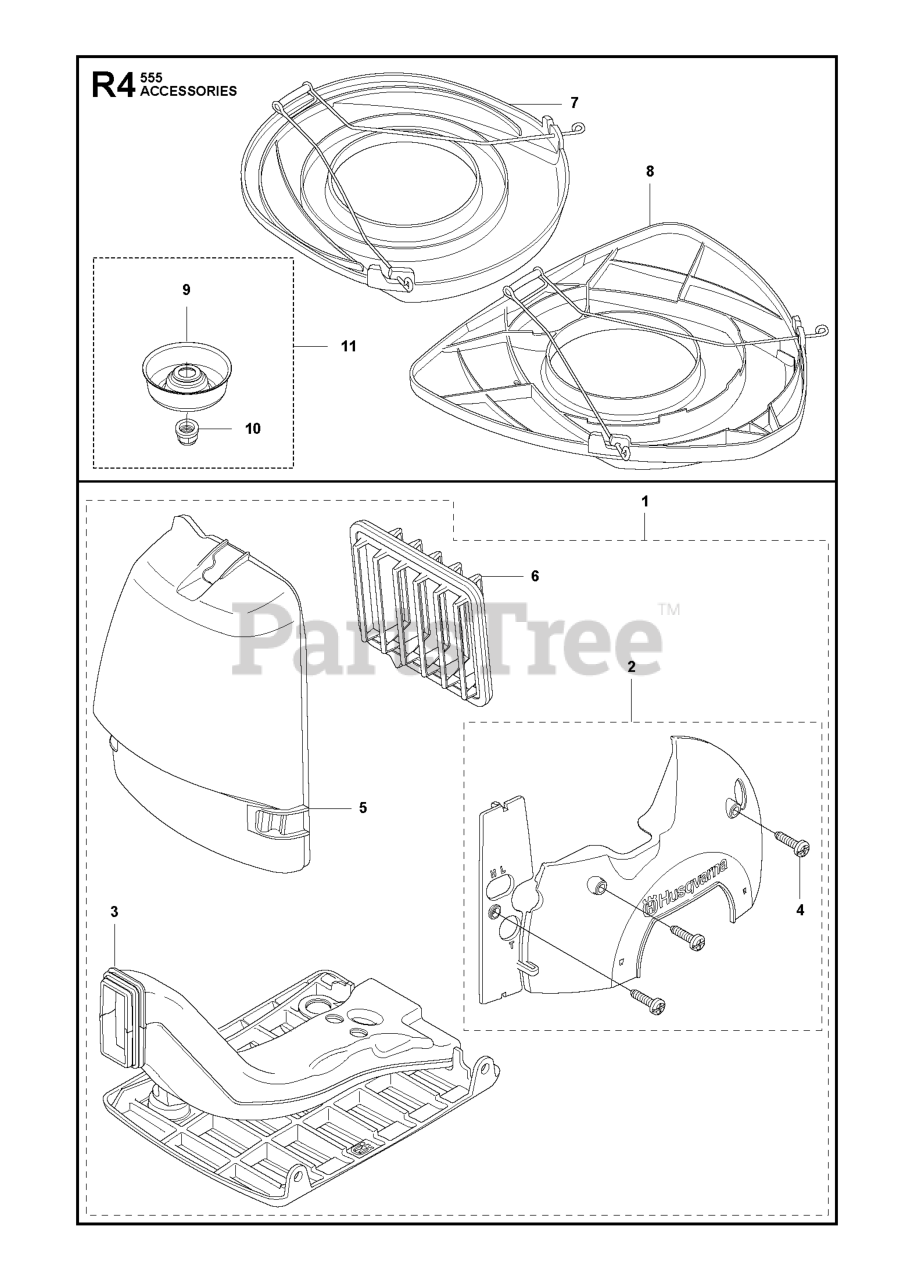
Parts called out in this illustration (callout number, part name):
1	WINTER KIT
2	WINTER COVER KPL VALID FROM RE
6	Filters
7	BLADE GUARD TRANSPORT
8	TRANSPORT GUARD
9	SUPPORT CUP
